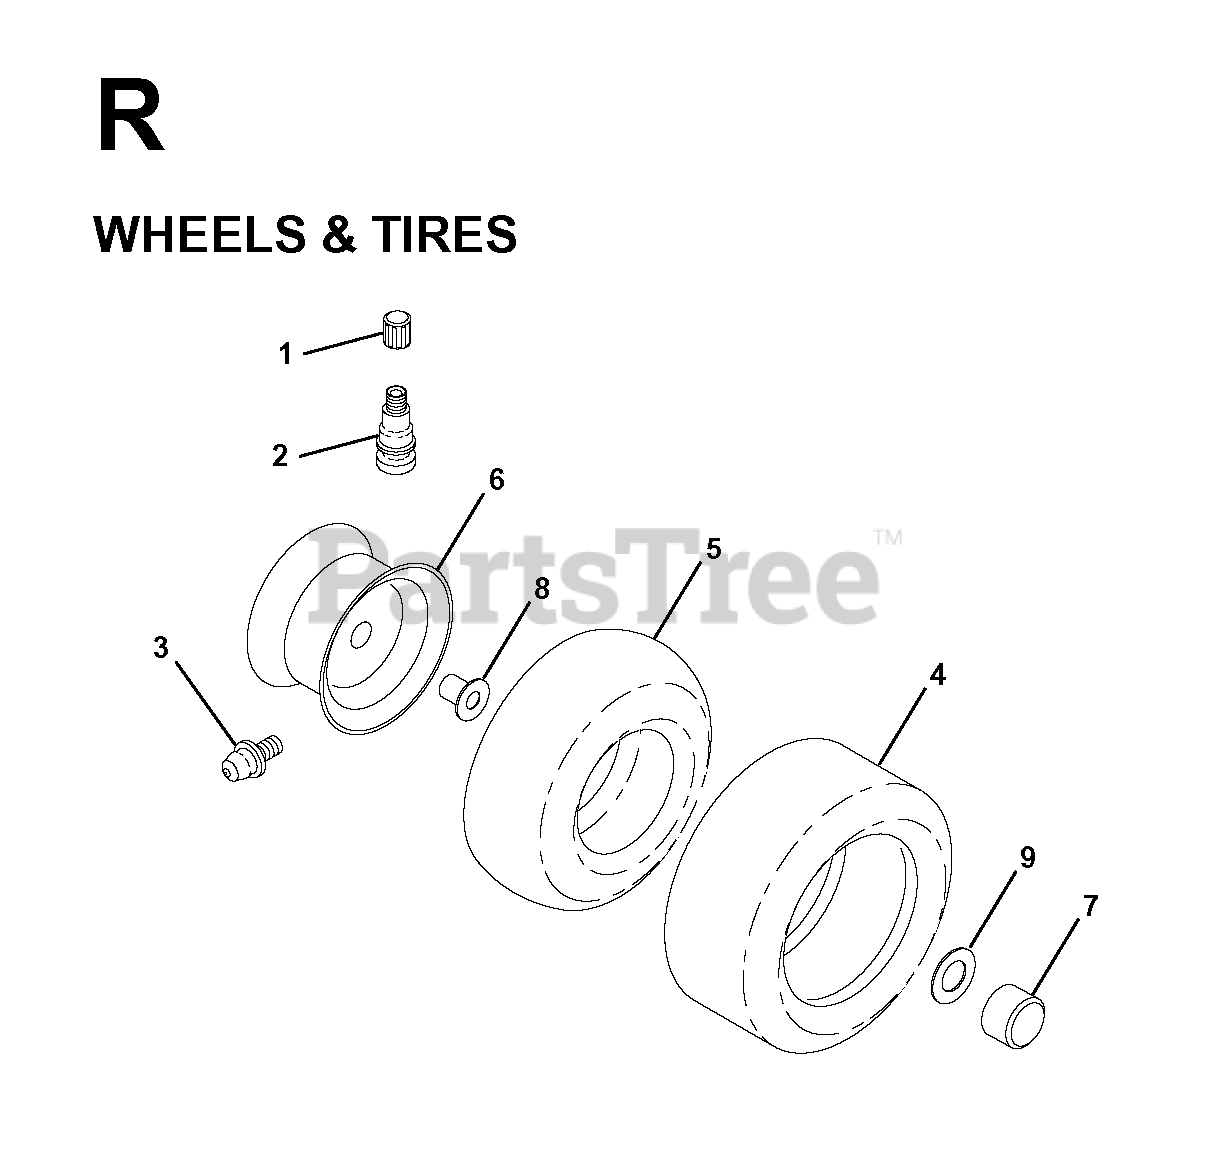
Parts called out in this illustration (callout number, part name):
1	VALVE CAP
2	VALVE STEM LT
3	FITTING LT
4	TIRE.TS 13X5-6
4	TIRE HEAVY DUTY
5	TUBE.5.3/4.5/6
5	TUBE.16X6.5/7.5-8
6	RIM
6	RIM REAR 8"
7	CAP-HUB FRONT LT
8	BEARING T
